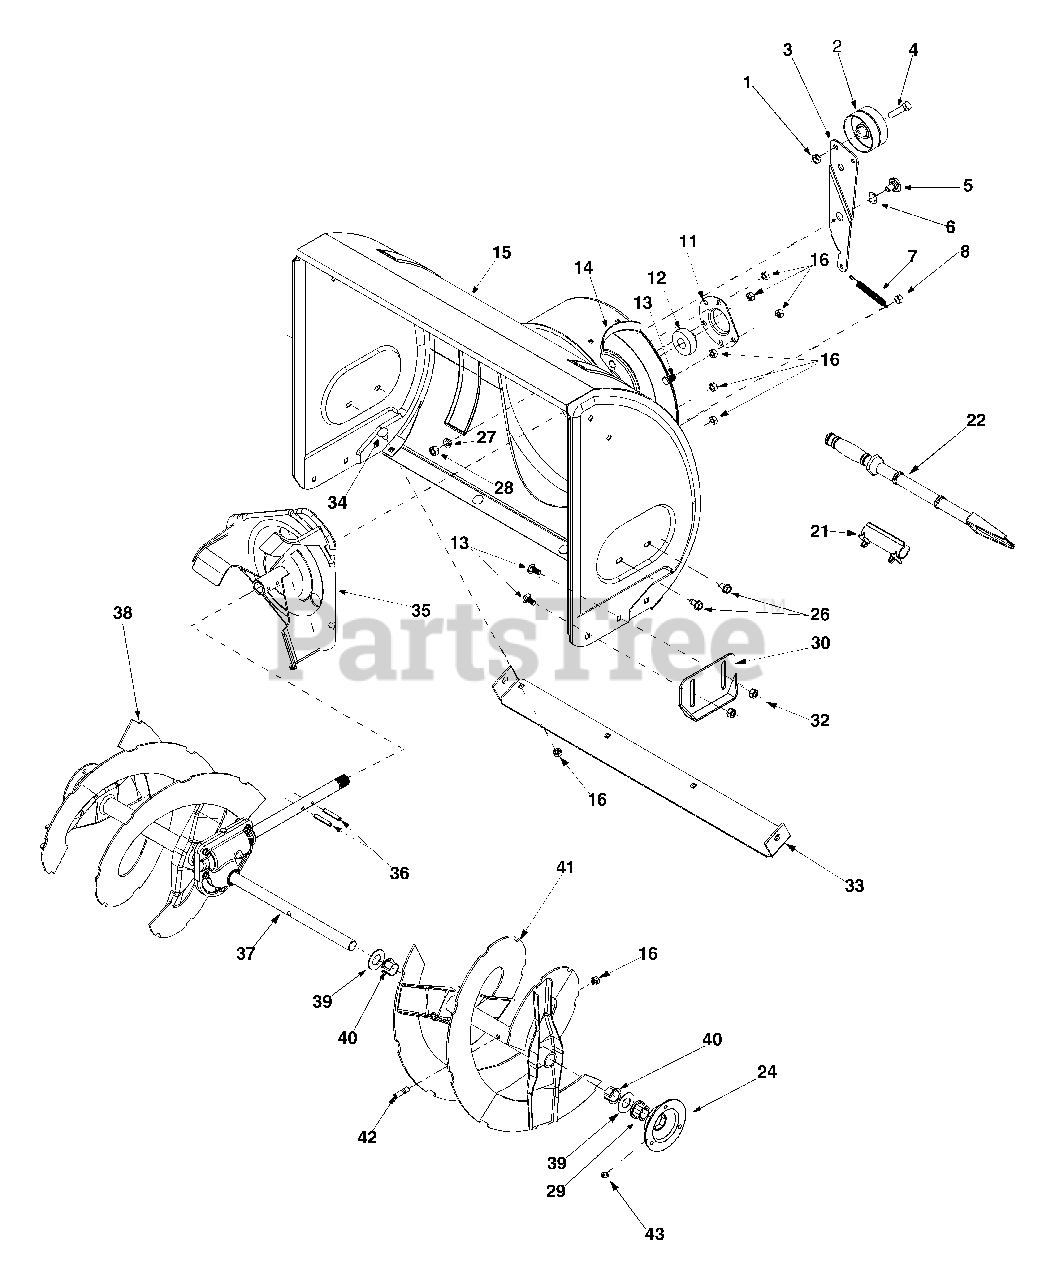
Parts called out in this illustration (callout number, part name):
1	Lock Jam Nut 3/8-24
2	Flat Idler
3	Auger Idler Arm
4	Hex Cap Screw 3/8-24 x 1.50
5	Shoulder Screw
6	Wave Washer
7	Extension Spring
8	Hex Nut 5/16-18
9	Carriage Bolt, 5/16-18 x 1.00
11	Housing
12	Ball Bearing
13	Carriage Bolt, 5/16-18 x.75
14	Chute Reinforcement
15	Auger Housing Assembly 28"
16	Flange Lock Nut 5/16-18
19	Flat Washer
21	Clean-Out Tool Mount
22	Clean-Out Tool
24	Bearing Housing
26	Hex Screw 5/16-12
28	Flange Lock Nut 3/8-16
29	Hex Flange Bearing
30	Skid Shoe
32	Flange Nut 5/16-18
33	Shave Plate
34	Carriage Bolt 5/16-18 x 1.00
35	Impeller Assembly
36	Pin
37	Gear Assembly Complete, 28"
38	Spiral Assembly RH
39	Flat Washer
40	Flange Bushing
41	Spiral Assembly LH
42	Shear Bolt 5/16-18 x 1.5
43	Lube Fitting
